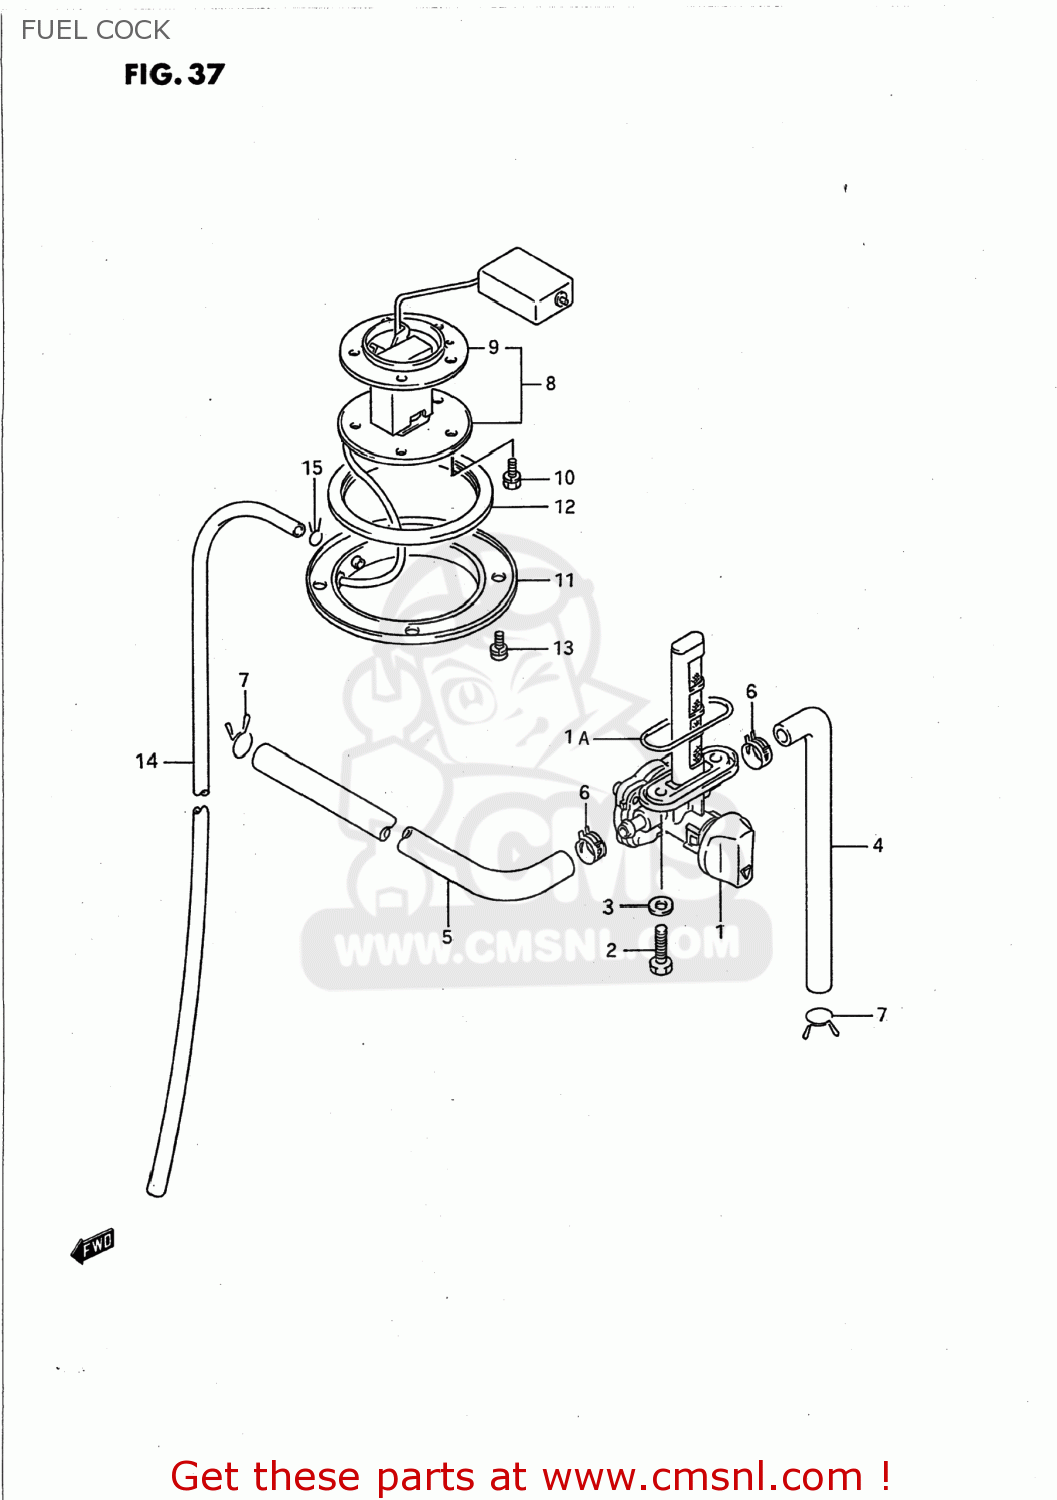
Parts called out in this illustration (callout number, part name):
1	COCK ASSY,FUEL
1A	O RING
2	BOLT(6X20)
3	GASKET(6.4X11.5X0.8) (NAS)
4	HOSE (7X12X150)
5	HOSE (7X12X330)
6	CLIP
7	CLIP
8	GAUGE ASSY,FUEL LEVEL SENDER
9	GASKET,FUEL LEVEL GAUGE (NAS)
10	BOLT
11	PLATE,FUEL DRAIN
12	GASKET,FUEL DRAIN PLATE (NAS)
13	BOLT
14	HOSE(5X8.2X2000)
15	CLIP
